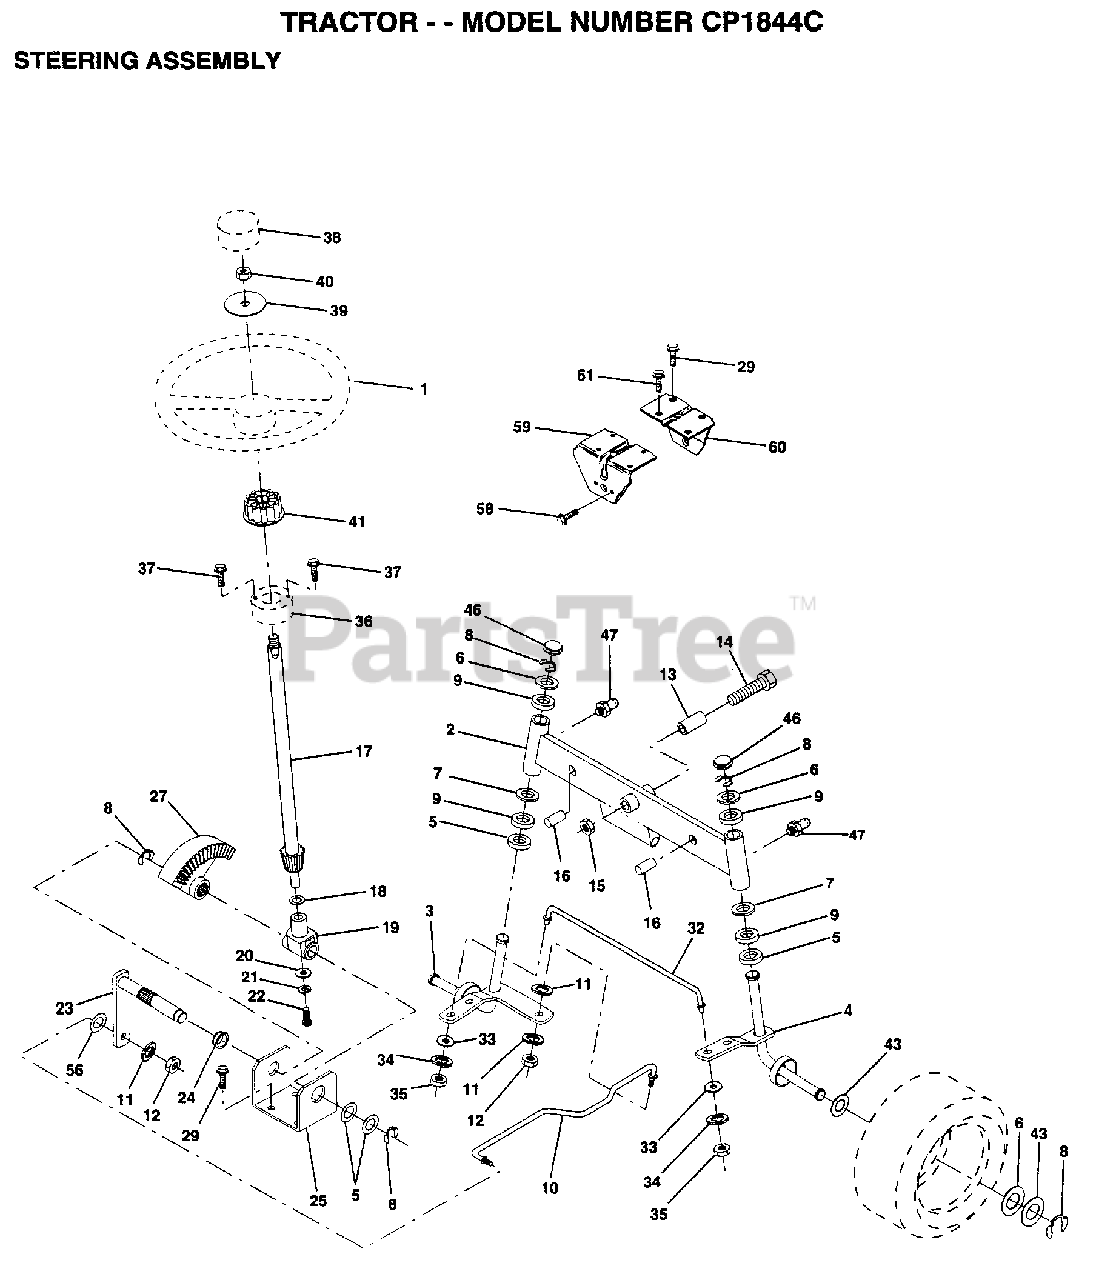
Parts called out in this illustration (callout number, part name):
2	AXLE ASM FRONT
5	WASHER .T
6	WASHER
7	WASHER
8	RING
9	COL. SRTG. BEAR.
11	LOCKWASHER
13	BEARING
14	BOLT LT
15	"NUT-LOC,FLANGE LT"
16	AXLE PIN
17	STEERING SHAFT
18	THRUST WASHER
19	SUPPORT.SHAFT
21	LOCKWASHER
22	"SCREW,SPECIAL"
24	NYLINER T
25	"BRKT,STEERING"
27	GEAR SECTOR
29	SCREW
32	ROD.TIE.19.75
33	WASHER M
34	LOCKWASHER
35	NUT.LOCK.5/16-24
36	BUSHING.STRG.3/4
37	SCREW.10-24X1/2
38	"INSERT,STR WHEEL"
39	WASHER
41	ADAPTER LT
43	WASHER
46	CAP
47	ZERK M
56	WASHER
58	SCREW LT
59	SUPPORT-SADDL T
60	SUPPORT.SADDLE.FT
61	SCREW SPECIAL
